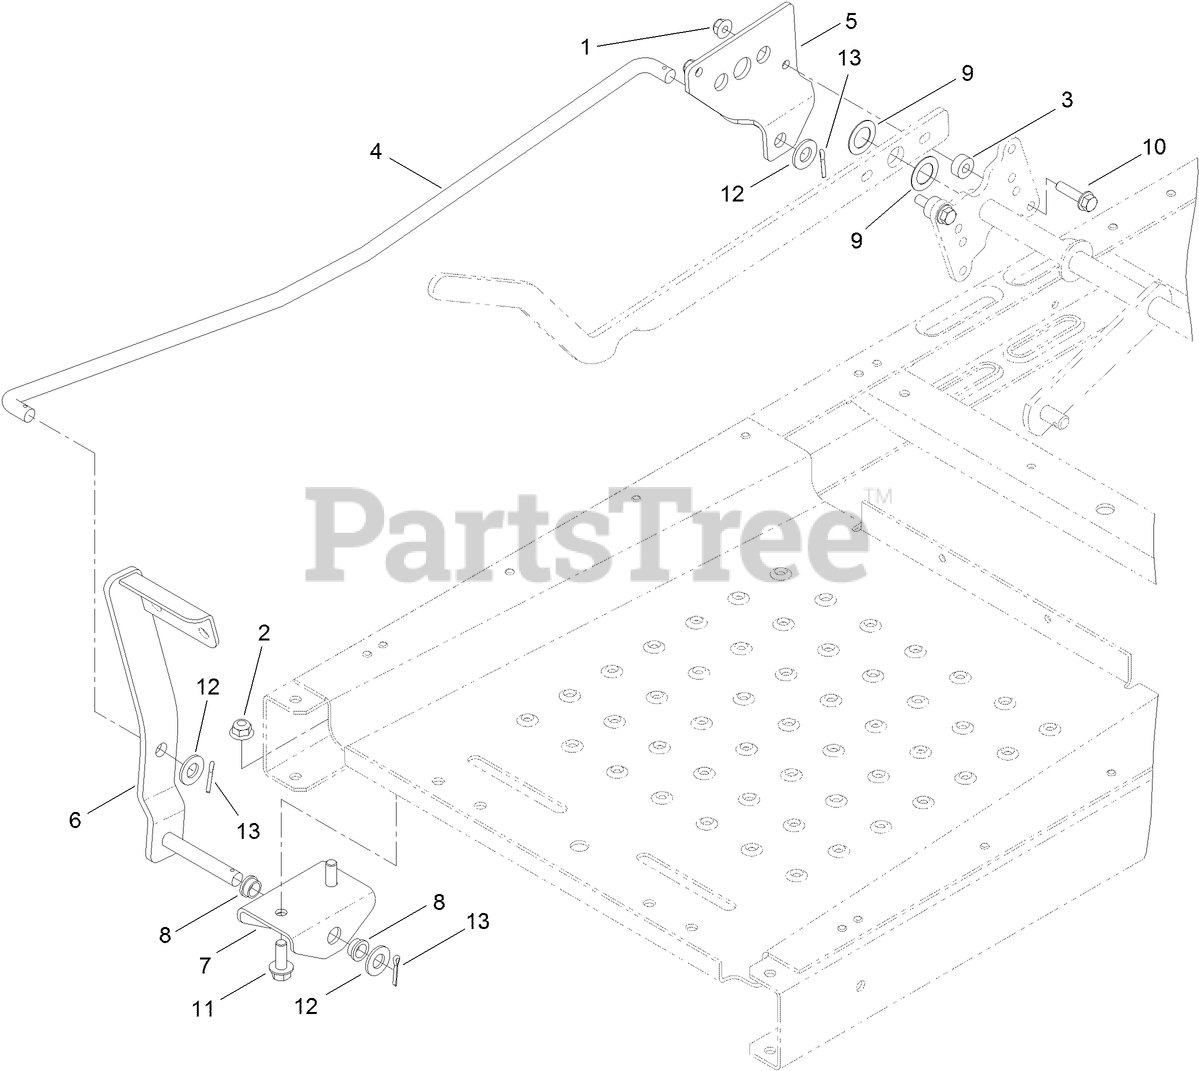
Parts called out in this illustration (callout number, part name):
1	NUT-HF, NI
2	NUT-HF, NI
3	SPACER
4	ROD-FOOTLIFT
5	PLATE-FOOTLIFT
7	BRACKET-FOOTLIFT
8	BUSHING-FLANGE
9	WASHER-THRUST
10	SCREW-HHF
11	SCREW-HHF
12	WASHER-FLAT
13	PIN-COTTER
